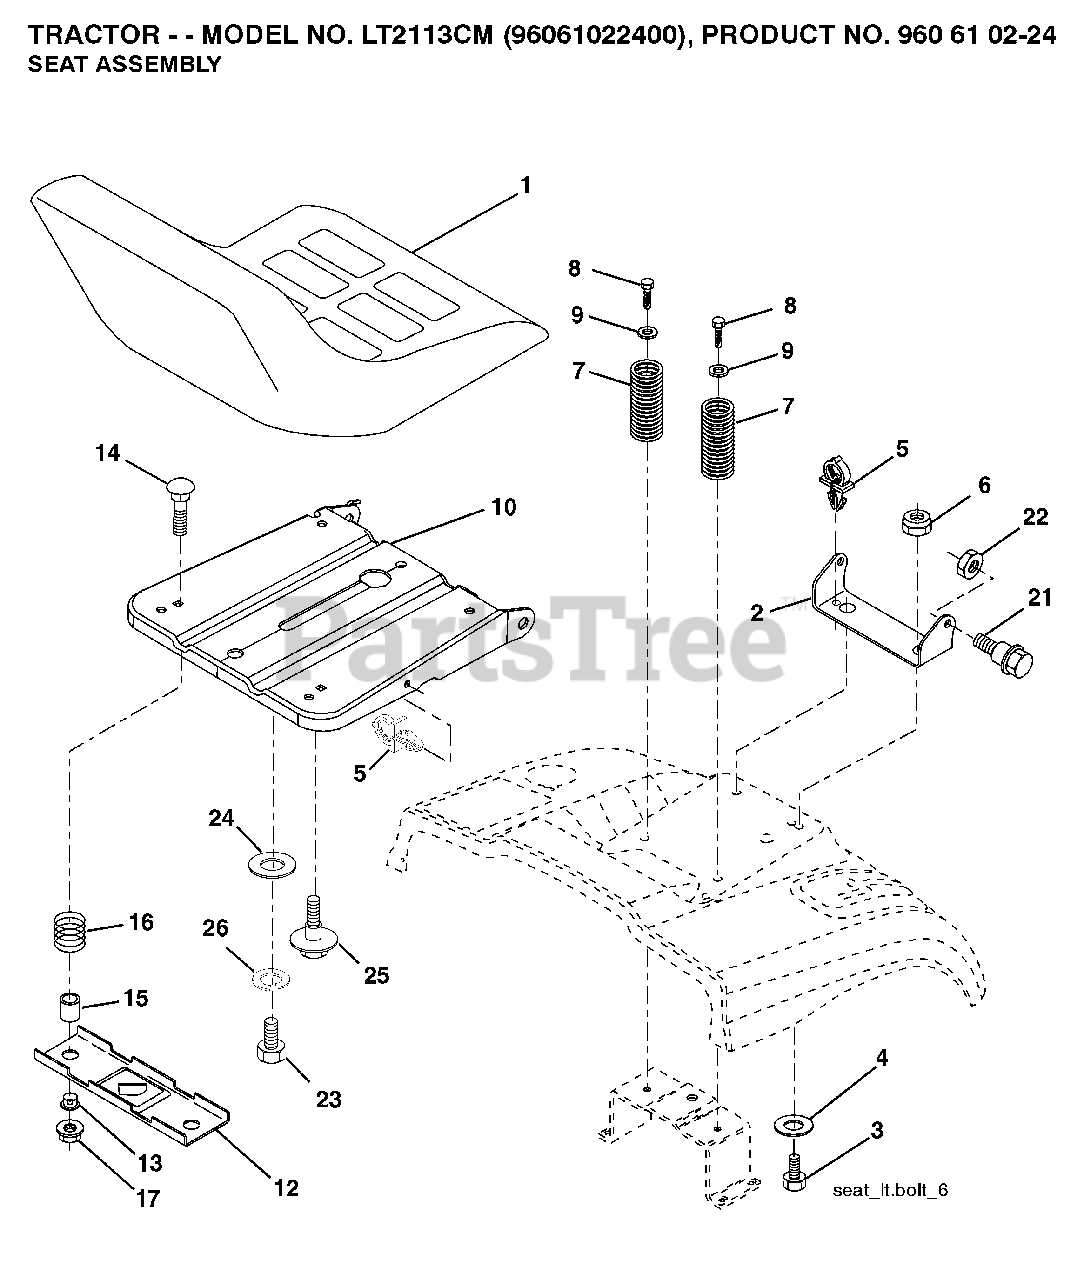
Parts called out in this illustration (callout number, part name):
1	SEAT.XG090.BLK.KB/BLT.NO-LOG
2	SEAT PIVOT BRKT
4	WASHER PM
5	PUSH CLIP
6	NUT
7	SPRING COMPRESSION
8	SCREW 3/8-16X1
9	WASHER
10	PAN.ASM.SEAT.1SLOT
12	BRKT.MNTNG.SWITCH.SEAT
14	BOLT.ROUND.HEAD.SQUARE.NECK
15	SPACER SPLIT 28X.96
17	NUT T
21	BOLT.SHOULDER.5/16-18
22	NUT.71038.31-18.HEX.NYLOCK
23	BOLT.HEX.BLACK
25	BOLT,SHOULD
26	LOCKWASHER
